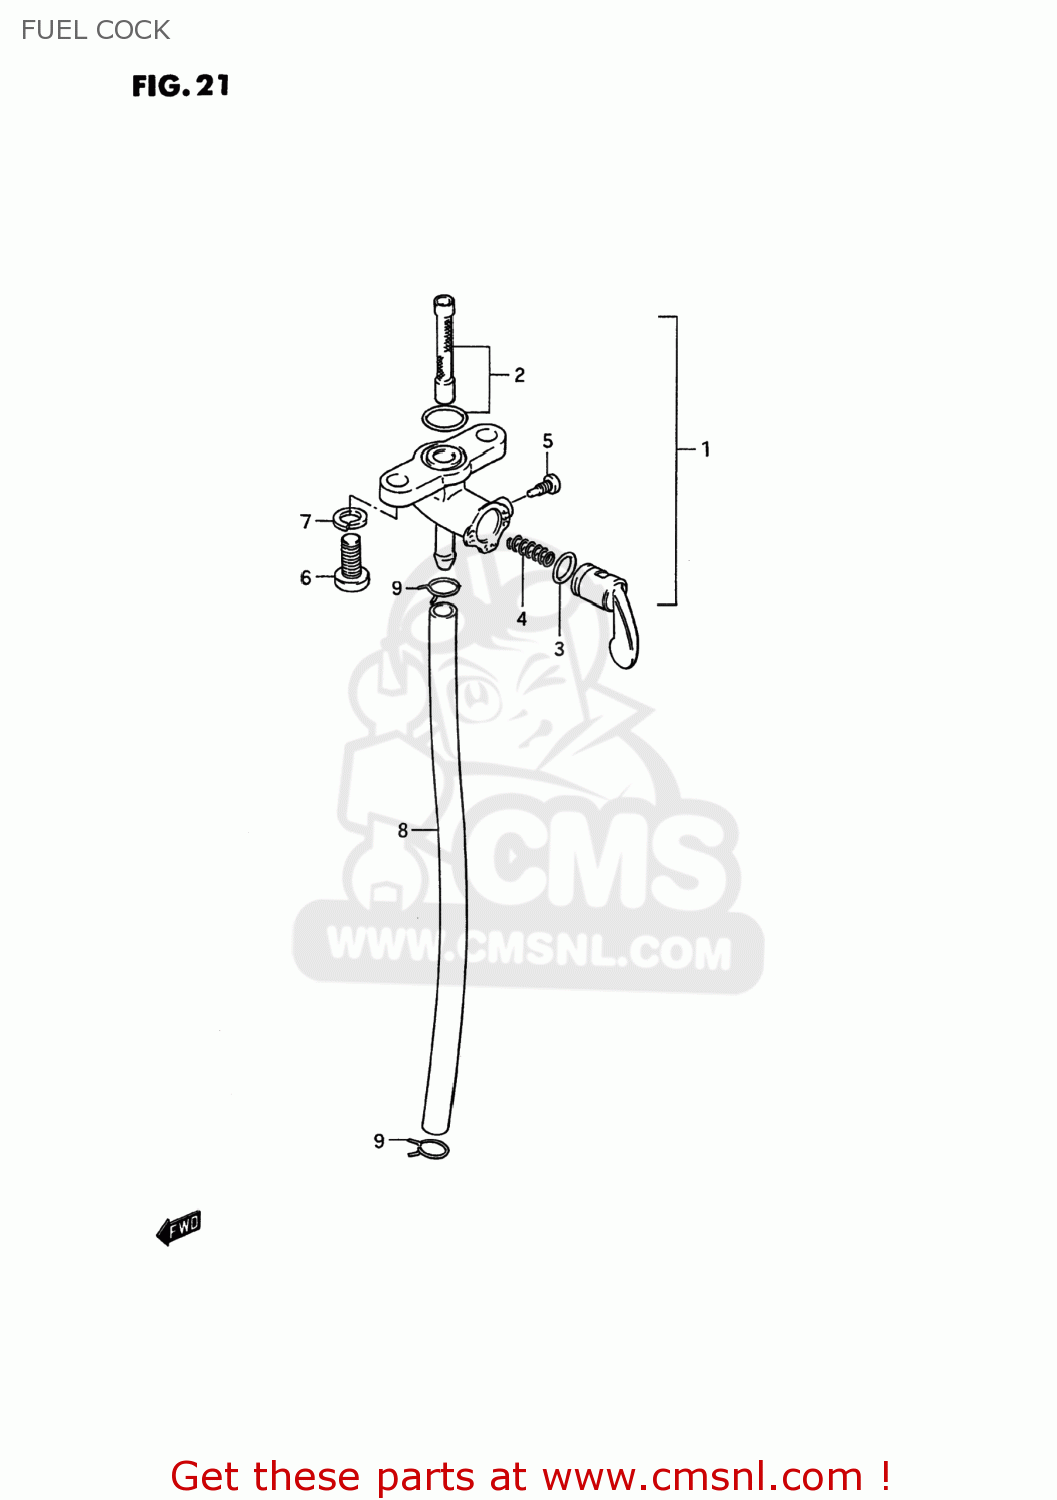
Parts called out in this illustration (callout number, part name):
1	COCK ASSY,FUEL
2	FILTER SET FUEL
3	O RING,LEVER
4	SPRING,FUEL COCK VALUE
5	SCREW
6	SCREW
7	WASHER,LOCK
8	HOSE
9	CLIP
